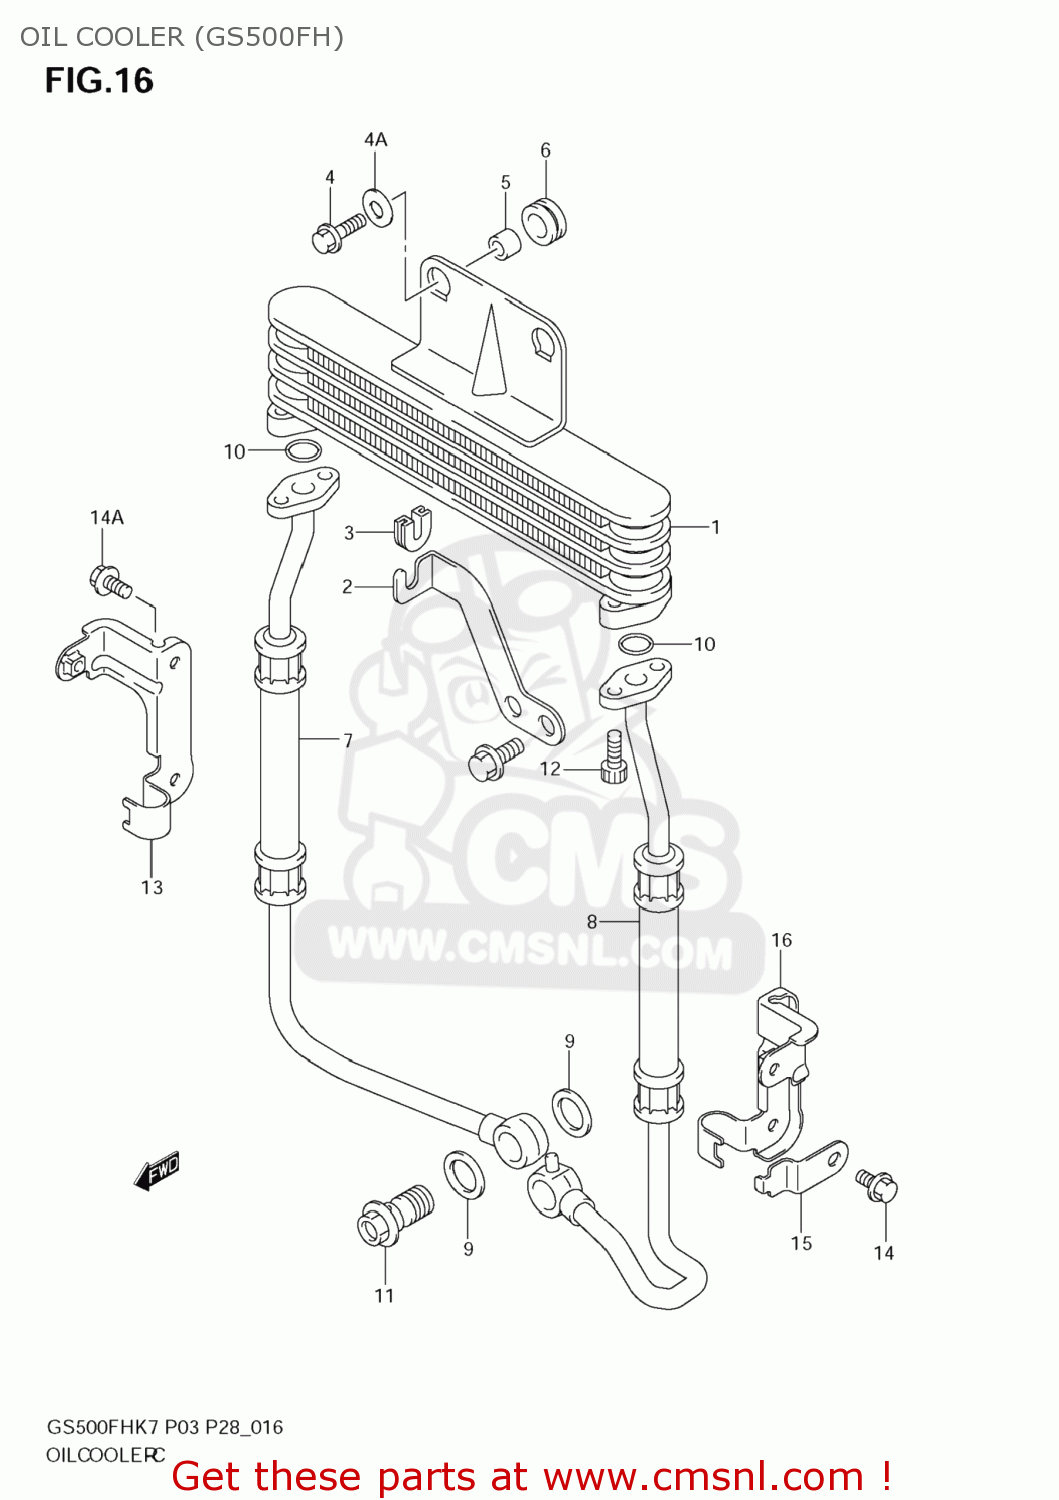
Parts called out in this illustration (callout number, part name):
1	COOLER ASSY,OIL
2	BRACKET,OILCOO
3	CUSHION
4	BOLT
4A	WASHER
5	SPACER(6.5X10X10)
6	CUSHION
7	HOSE,OIL COOLER,R
8	HOSE,OIL COOLER,L
9	GASKET(14X20X1.5) (NAS)
10	O-RING
11	BOLT UNION
12	BOLT 6X16
13	CLAMP, OIL HOS
14	BOLT UH125&200
14A	BOLT
15	GUIDE, OIL HOS
16	CLAMP, OIL HOS
